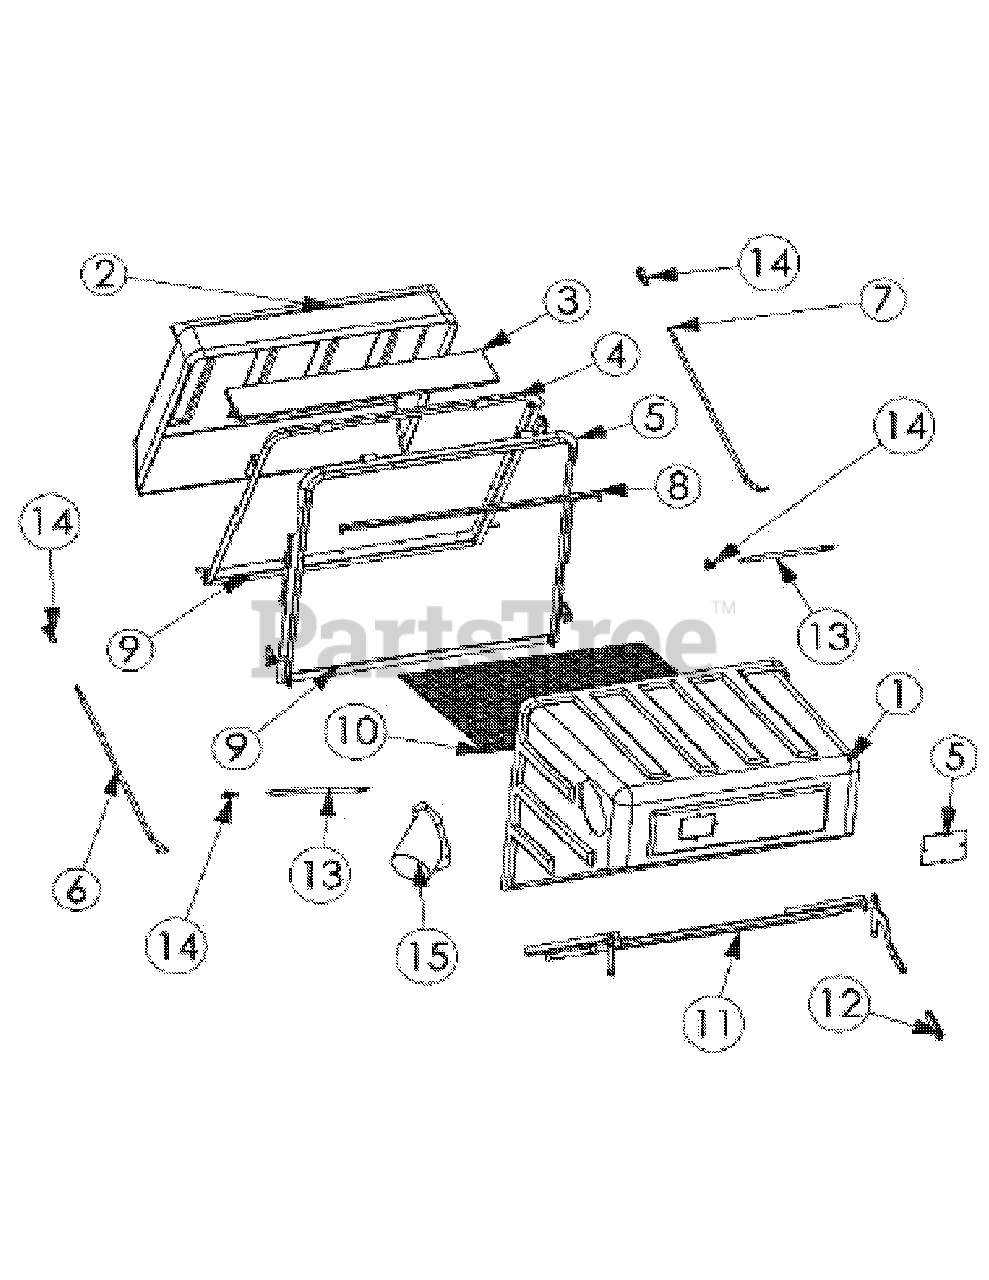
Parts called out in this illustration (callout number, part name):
1	Catcher Body
2	Plastic Door
3	Door Vent Spacer
4	Door Frame Opening
5	Catcher Frame Opening
6	Hinge Rod Right
7	Hinge Rod Left
8	Screen Support
9	Opening Frame Bottom
11	Dump Lever Assy.
12	Dump Lever Handle
14	3/8"x1 1/8" Clevis Pin
15	Intake Tube
